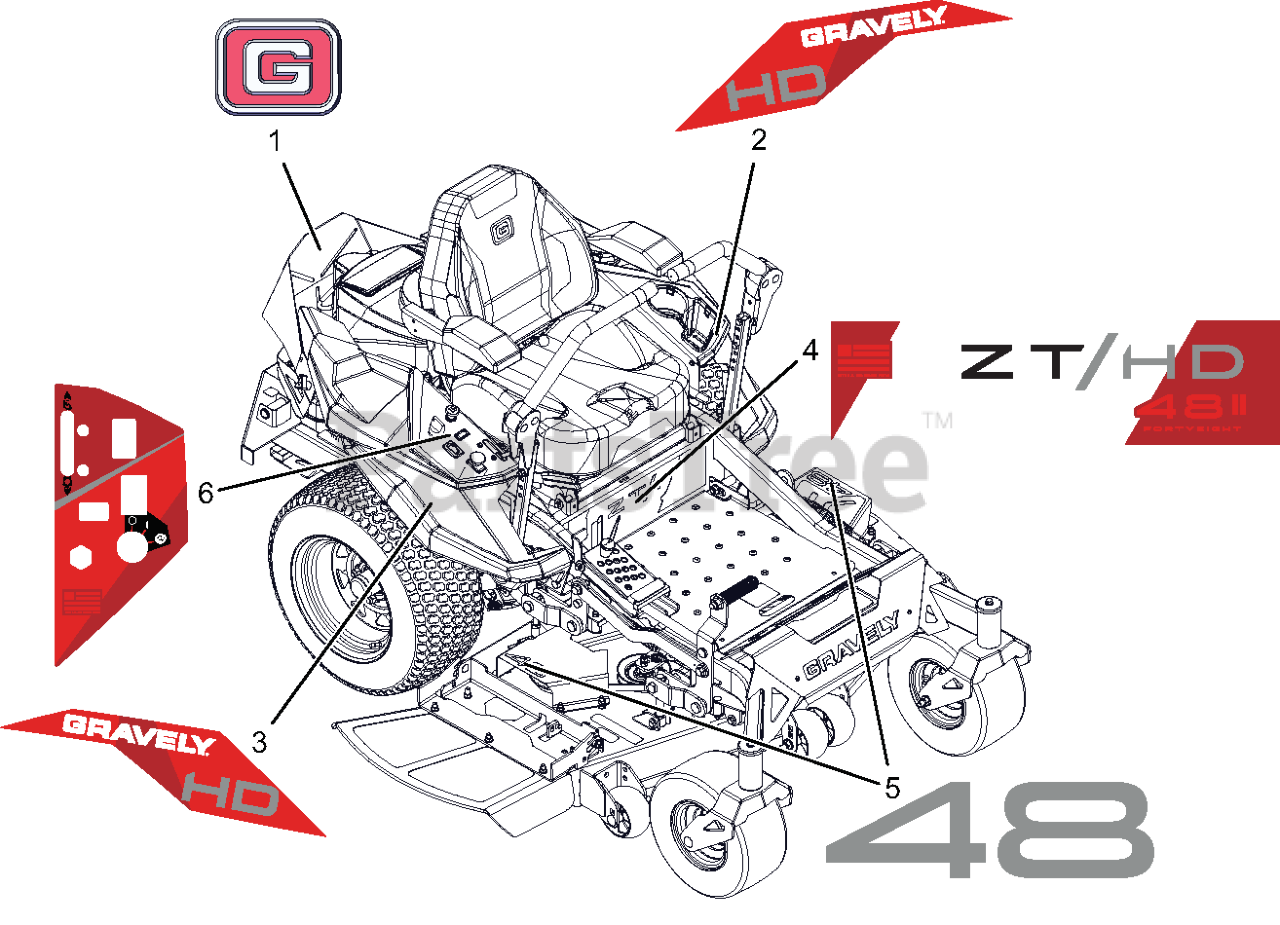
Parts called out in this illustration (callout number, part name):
1	DECAL, GRAVELY BRAND
2	DECAL, FENDER LH - HD
3	DECAL, FENDER RH - HD
4	DECAL, ZT/HD - 48
5	DECAL, DECK - 48
6	DECAL, CONTROL PANEL
